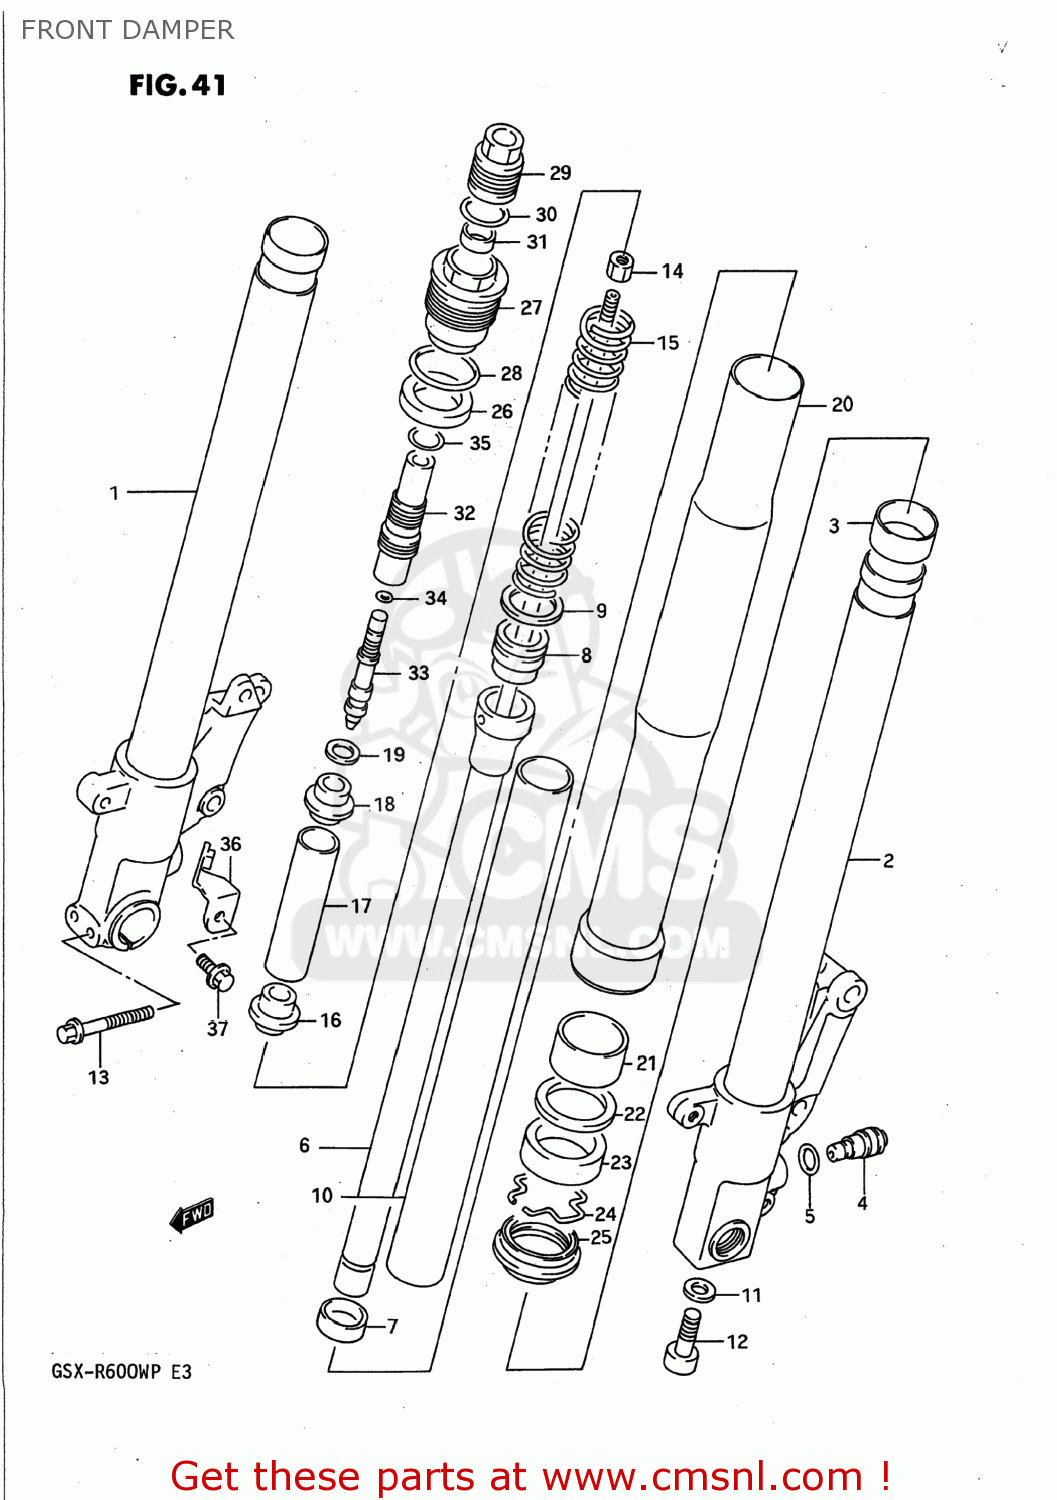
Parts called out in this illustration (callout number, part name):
1	TUBE,INNER,RIGHT
2	TUBE,INNER,LEFT
3	BUSH,SLIDE
4	PIECE,ADJUSTER
5	O RING
6	DAMPER,FRONT
7	PLATE,CENTERING
8	JOINT,SPRING,LOWER
9	RING,FRONT FORK PISTON
10	SPACER,SPRING LWR
11	WASHER(10X15X1.5)
12	BOLT
13	BOLT
14	NUT
15	SPRING,MAIN
16	JOINT,SPRING
17	SPACER,SPRING
18	JOINT,SPRING
19	GUIDE,SPRING
20	TUBE,OUTER
21	BUSH,GUIDE
22	SPACER,SEAL
23	SEAL,OIL
24	CIRCLIP,FORK OIL SEAL
25	DUST SEAL,FRONT FORK
26	RUBBER,SEAT
27	BOLT,FORK
28	O RING,FORK BOLT
29	ADJUSTER,SPRING
30	O RING
31	PLATE,SPRING ADJUSTER
32	CASE,ADJUSTER
33	PIECE,ADJUSTER UPR
34	O RING
35	RING,STOPPER
36	PLATE,FRONT FENDER,LEFT
37	BOLT 8X12
